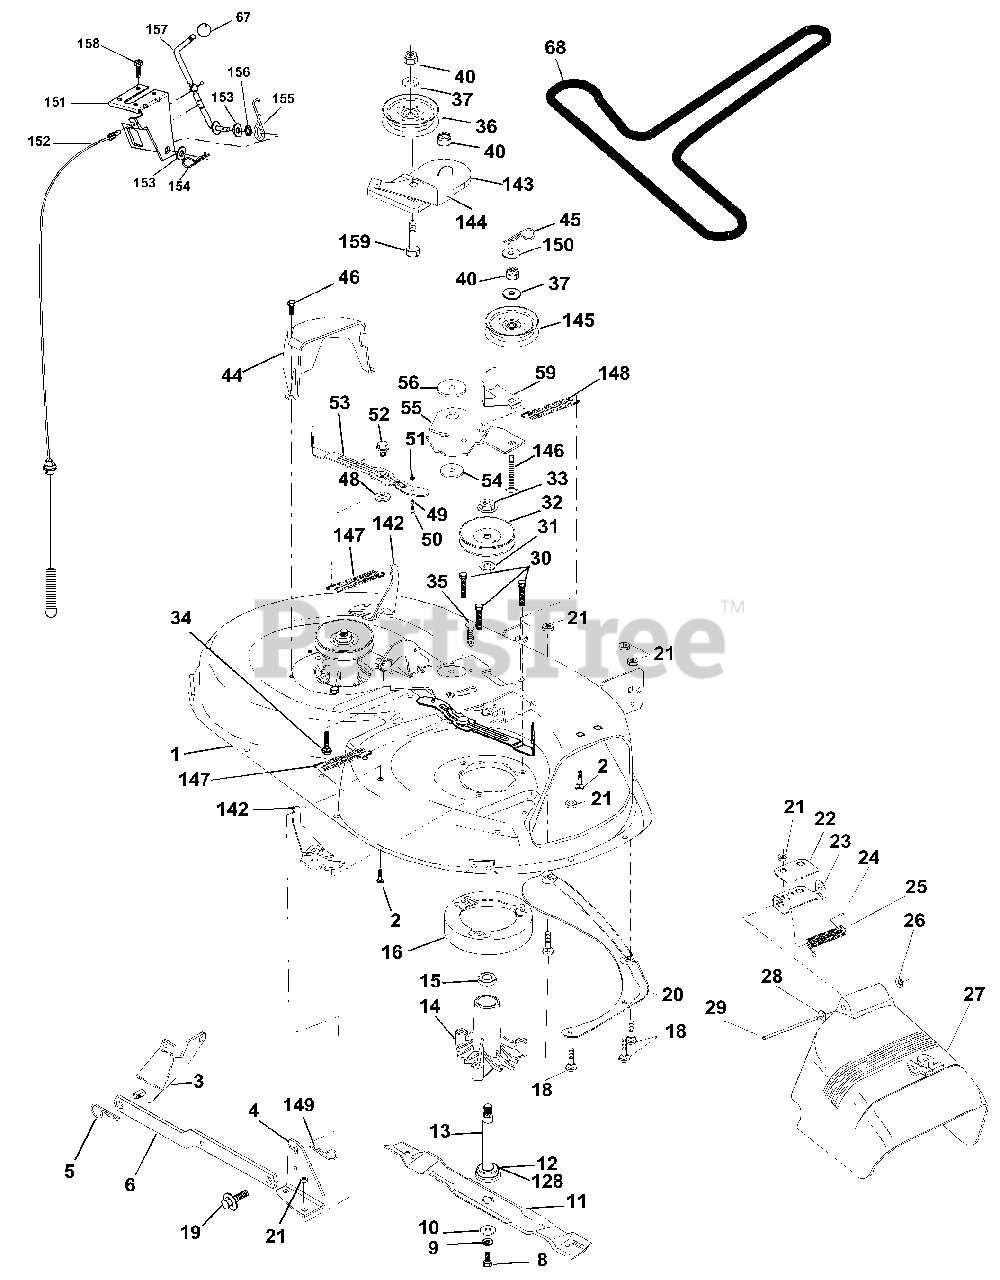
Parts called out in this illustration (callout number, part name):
1	Mower Deck Assembly, 42"
2	Bolt
3	Bracket Asm Fr. Sway Bar 3/42
4	Bracket Asm Deck 42" Sway Bar
5	Retainer Spring
6	Arm, Suspension, Rear
8	Bolt 3/8-24 x 25 Grade 8 patched
9	Washer, Lock
10	Washer,Hardened
11	Blade Mower 42" Hi-Lift Std
12	Bearing, Ball #6204
13	Shaft Assembly, Mandrel, Vented
14	Housing, Mandrel, Vented
15	Bearing, Ball, Mandrel
16	Stripper, Vented Mower Deck
18	Bolt, Carriage 5/16-18 x 5/8
19	Bolt, Shoulder
20	Baffle, Vortex
21	Nut
22	Stiffener Bracket
23	Bracket, Deflector Mower 42"
24	Cap, Sleeve 80 x 112 Blk Mower
25	Spring, Torsion, Deflector 2 52
26	Nut, Push Phos & Oil
27	Shield, Deflector 42" Blk
28	Washer 11/32 x 5/8 x 16 Gauge
29	Rod, Hinge 42" 6 75 W/G
30	Screw Thdrol Washer Head
31	Washer, Spacer Mower Vented
32	Pulley, Mandrel
33	Nut, Toplock 9/16
34	Bolt
35	Fastener, Christmas Tree
36	Pulley, Idler, Flat
37	Washer 13/32 x 13/16 x 16 Gauge
40	Nut
44	Guard, Mandrel, LH
45	Retainer
46	Screw, Thdrol 1/4-20 x 5/8 T
48	Washer, Hardened
49	Roller Assembly, Cam Follower
50	Bolt, Shoulder #10-24 Grade 5
51	Locknut
52	Bolt, Shoulder 5/16-18 UNC
53	Arm Assembly, Pad, Brake
54	Washer, Hardened
55	Arm, Idler
56	Spacer, Retainer
59	Guard TUV Idler
67	Knob Round
68	V-Belt, 42" Mower
128	Washer, Felt
142	Arm Spring Brake Mower
143	Bracket Arm Idler 42"
144	Keeper Belt 42" Clutch Cable
145	Pulley Idler Flat
146	Bolt Carriage Idler
147	Spring Extension
148	Spring Return Idler
149	Retainer Spring Yellow
150	Washer 9/32 x 3/4 x 16 Ga.
151	Bracket Clutch Cable
152	Clutch Cable 42"
153	Washer Flat 3/8" Type B
154	Spring Retainer
155	Spring Retention LVR CLTCH CAB
156	Spacer Clutch Cable
157	Rod Clutch Cable 3/8"
158	Screw Hex Thd Cut 1/4-20 x 5/8
159	Bolt Rdhd Sqn 3/8-16 UNC x 1-3/4
